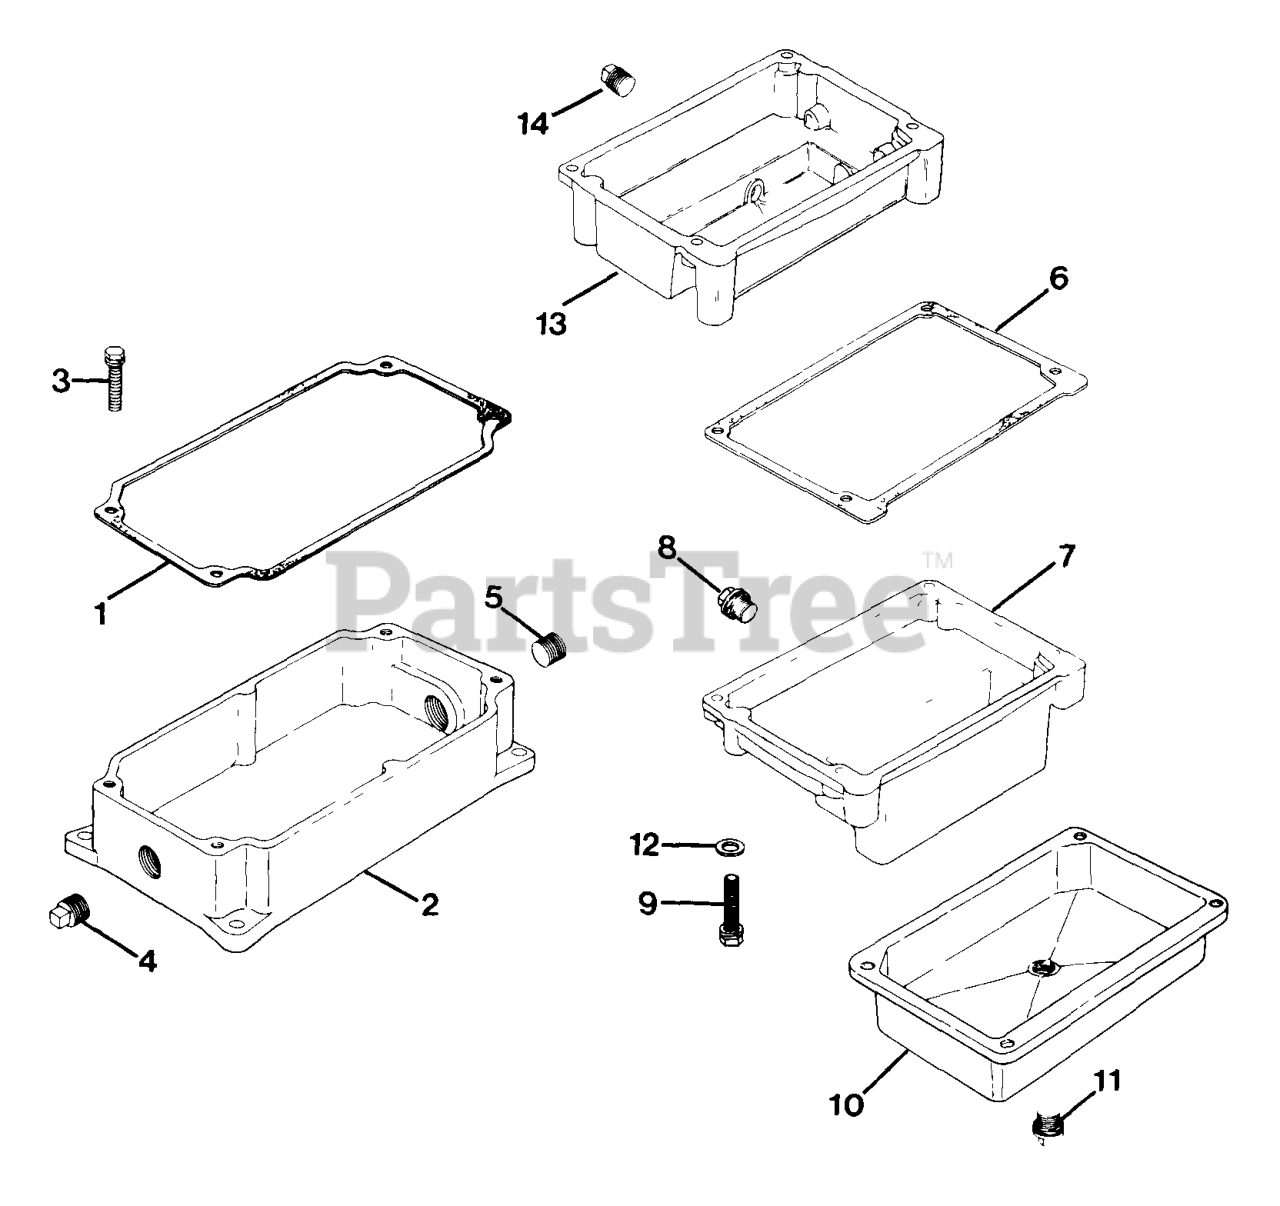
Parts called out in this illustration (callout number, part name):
1	GASKET, OIL PAN
2	BASE - DISCONTINUED
3	SCREW, SEMS 3/8-16X1-1/4" - DISCONTINUED
4	PLUG,PIPE SQ HD 3/4" USE 25 139 56-S
5	PLUG,PIPE SQ HD 3/4" USE 25 139 56-S
